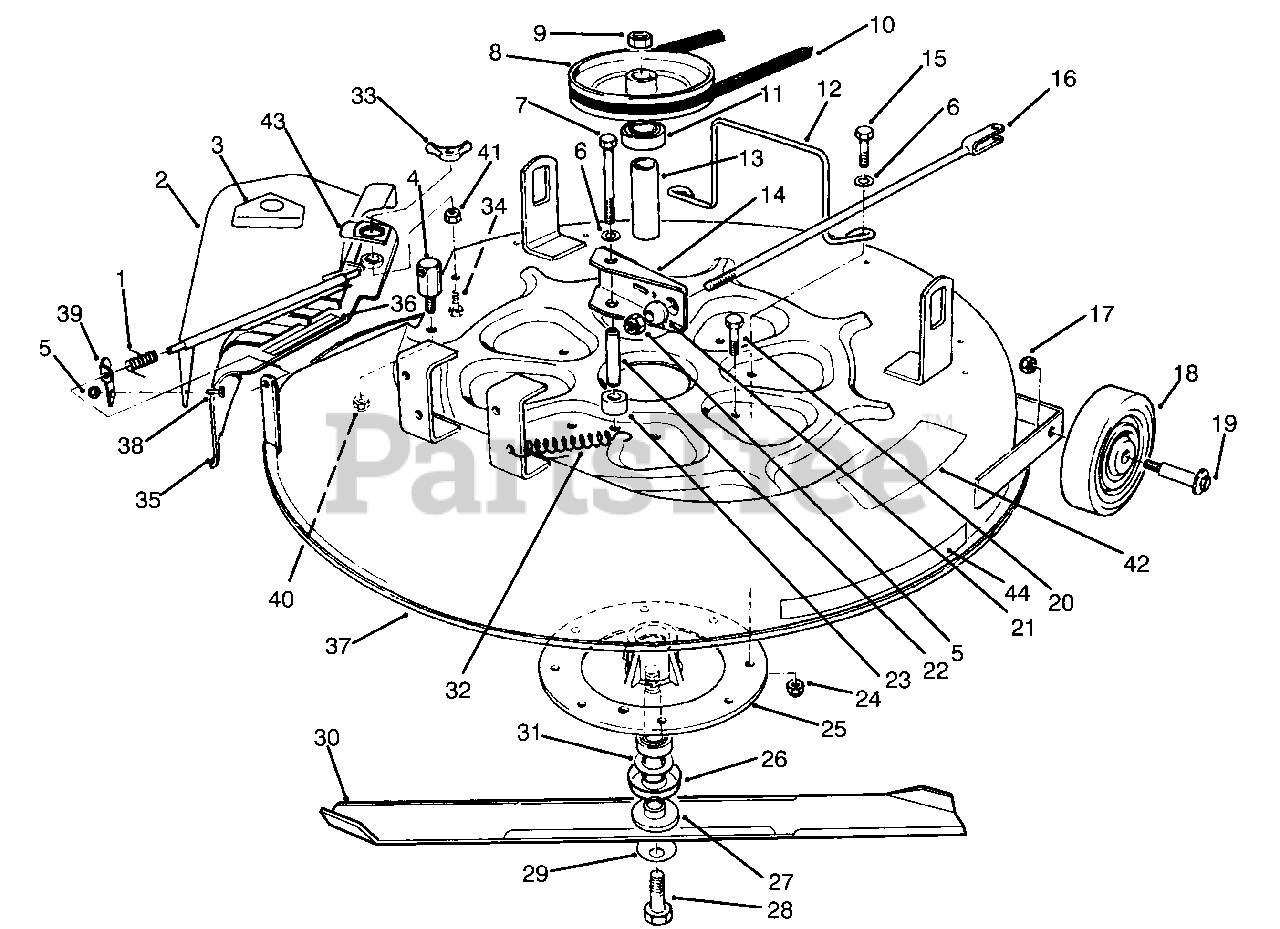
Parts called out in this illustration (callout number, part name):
2	Deflector (Incl. Ref. #3)
3	Decal-Danger
4	Post-Pivot
5	Nut-Lock
6	Washer-Lock
7	Screw-Cap Hex. Hd.
8	Pulley-Deck
9	Nut-Hex.
10	V-Belt
11	Bearing-Ball
12	Guide-Belt
13	Spacer-Bearing
14	Assy.-Brake, Deck
15	Screw-Cap Hex. Hd.
16	Rod W.A.-Brake, Deck
17	Nut-Lock
18	Wheel-Deck
19	Bolt-Wheel
20	Screw-Cap Hex. Hd.
21	Ball-Swivel
22	Post-Mount, Brake
23	Spacer-Brake, Deck
24	Nut-Lock
25	Hub-Spindle
26	Shield-Bearing
27	Shaft-Spindle
28	Bolt-Blade
29	Washer-Belleville
30	Blade-Power Mulch
31	Spacer-Spindle
32	Spring-Brake
33	Nut-Wing
34	Screw-Cap Hex. Hd.
35	Cover-Power Mulch
36	Decal-Warning
37	Deck
38	Screw-Cap Hex. Hd.
39	Bracket-Deflector
40	Nut-Lock
41	Nut-Lock
42	Decal-Danger
43	Tab-Hold Down
44	Decal-Power Mulch
